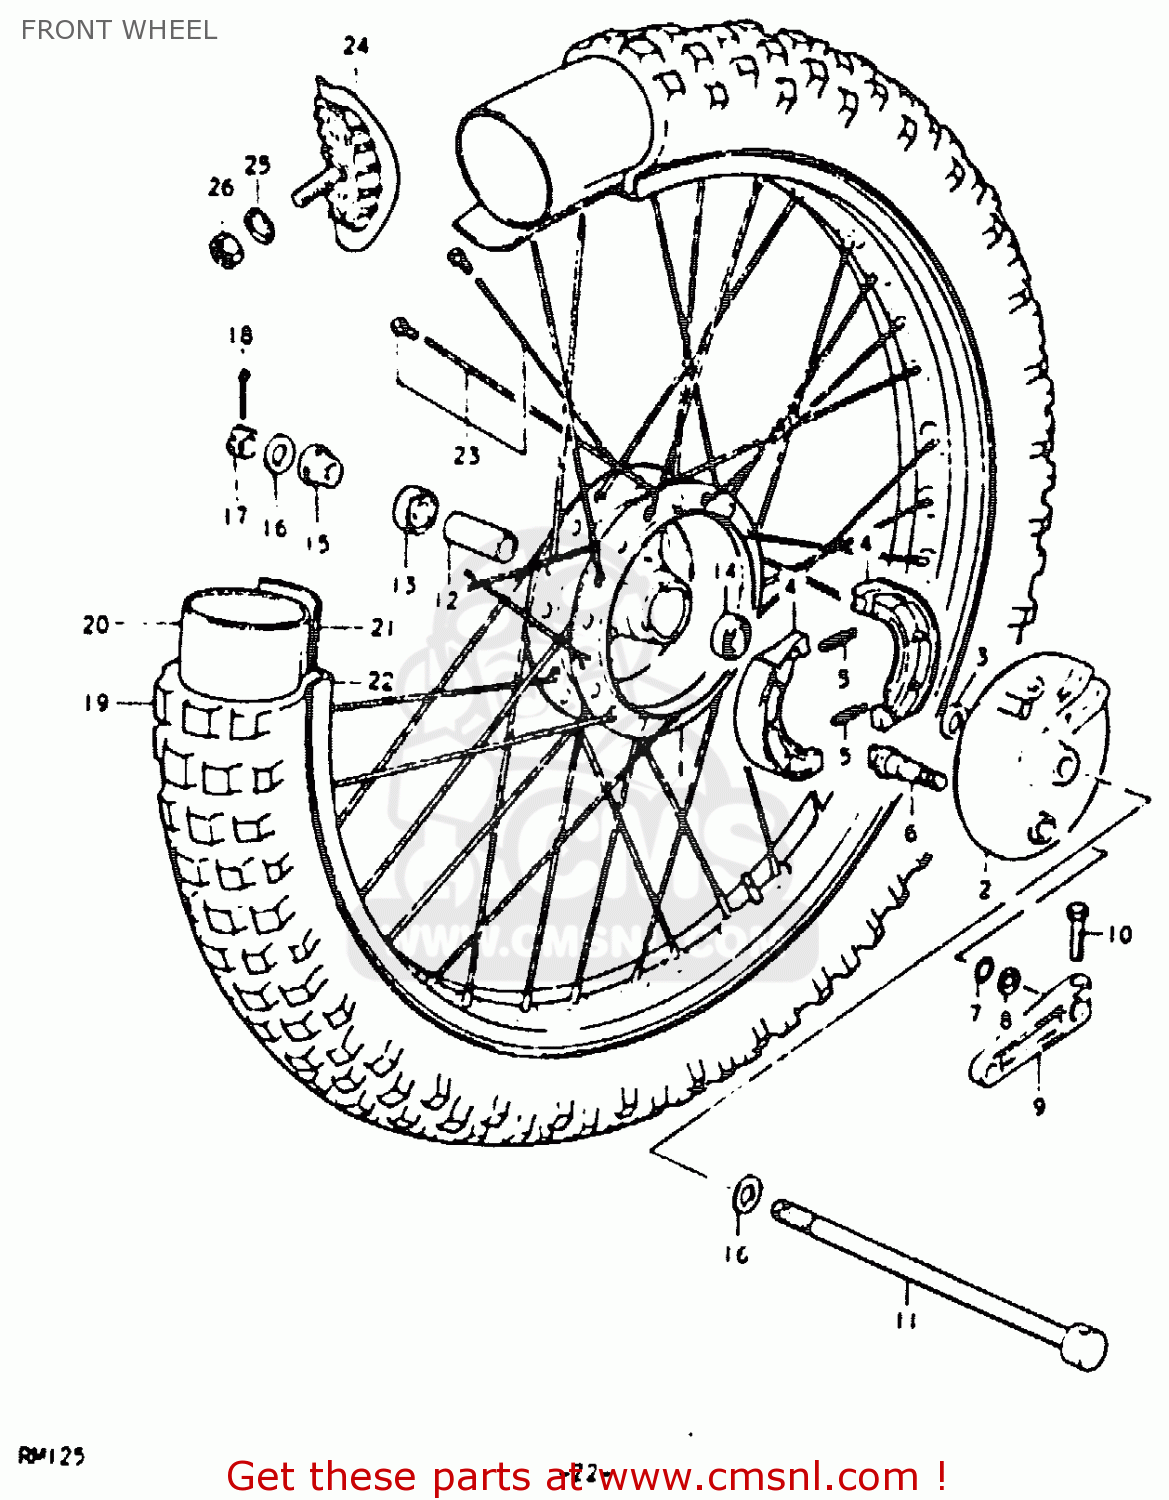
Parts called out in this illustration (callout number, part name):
1	HUB,FRONT
2	PANEL,FRONT HUB
3	BOSS
4	SHOE,BRAKE
5	SPRING(L:34)
6	CAM,FRONT BRAKE
7	O RING(D:2.5,ID:11.4)
8	WASHER(12.5X20X1)
9	LEVER,FRONT BRAKE CAM
10	BOLT
11	AXLE,FRONT
12	SPACER (12.6X19X52)
13	BEARING, RH
14	BEARING
15	SPACER,FRONT AXLE,RIGHT
16	WASHER
17	NUT, REAR AXLE
18	COTTER PIN
19	TIRE,FRONT
20	TUBE,INNER
21	PROTECTOR,WHEEL,INNER
22	RIM,FRONT WHEEL
23	SPOKE SET,FRONT
24	STOPPER,BEAD
25	WASHER
26	NUT
